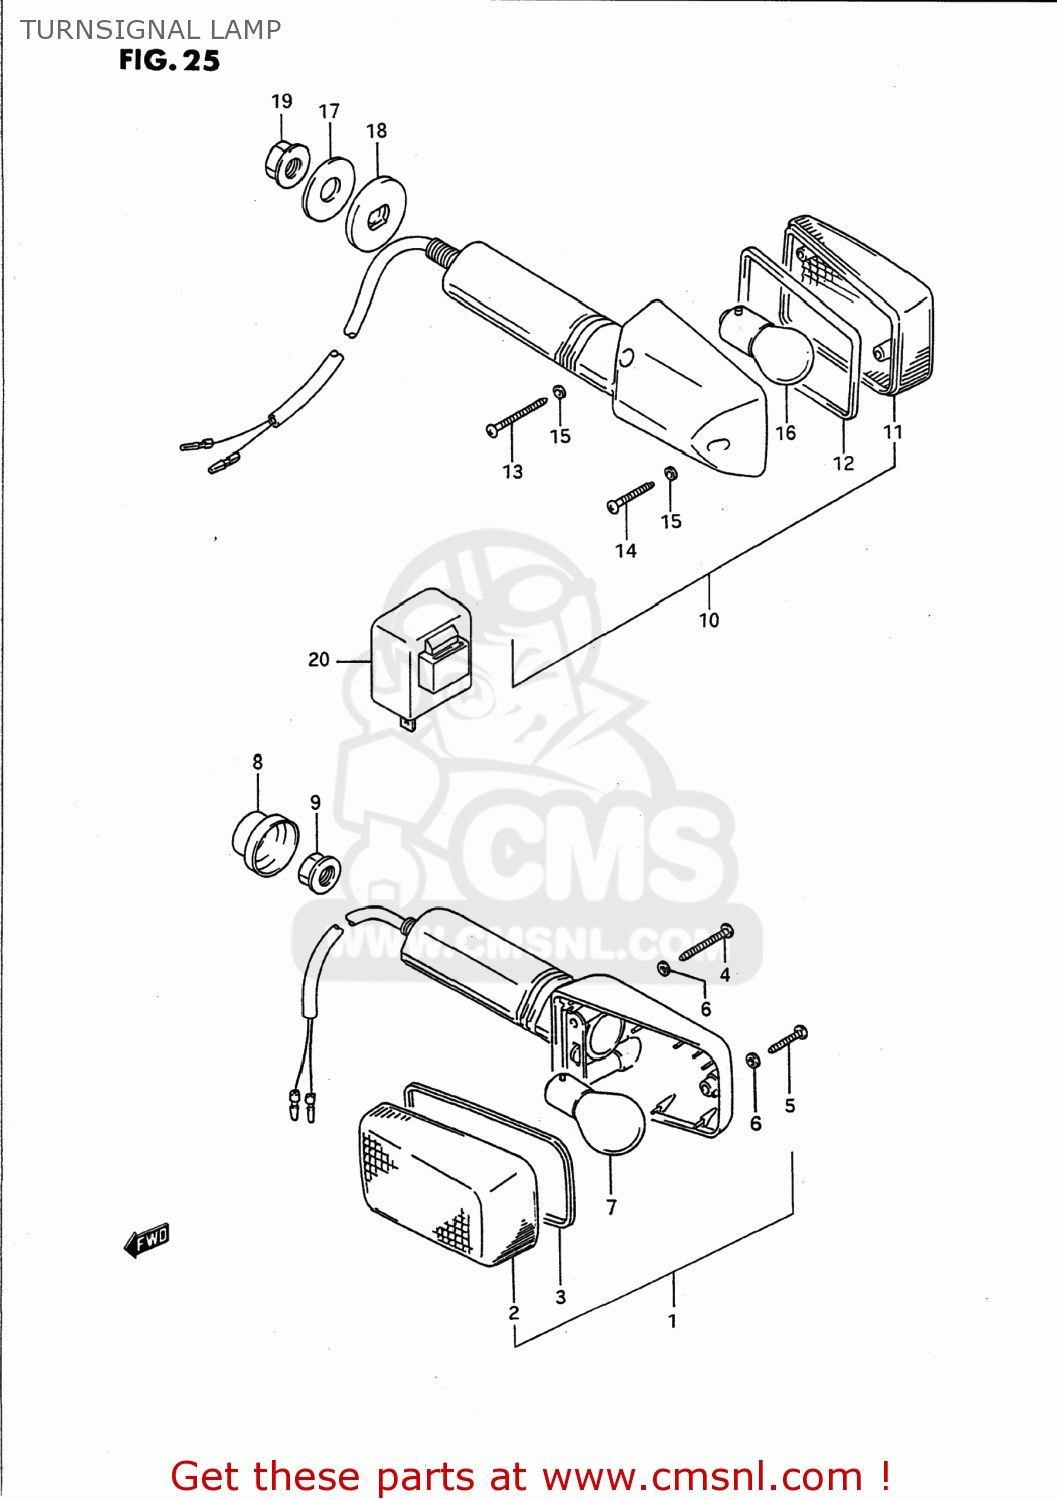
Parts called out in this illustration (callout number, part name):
1	LAMP ASSY,FR TURN SIGNAL
2	LENS
3	GASKET (NAS)
4	SCREW(3X30)
5	SCREW
6	GASKET (NAS)
7	BULB(12V21W)
8	CAP,TURNSIGNAL LAMP
9	NUT
10	LAMP ASSY,FR TURN SIGNAL
11	LENS
12	GASKET (NAS)
13	SCREW(3X30)
14	SCREW
15	GASKET (NAS)
16	BULB(12V21W)
17	WASHER(10.5X30X3.2)
18	SPACER,RR TURNSIGNAL
19	NUT
20	RELAY,TURN SIGNAL
